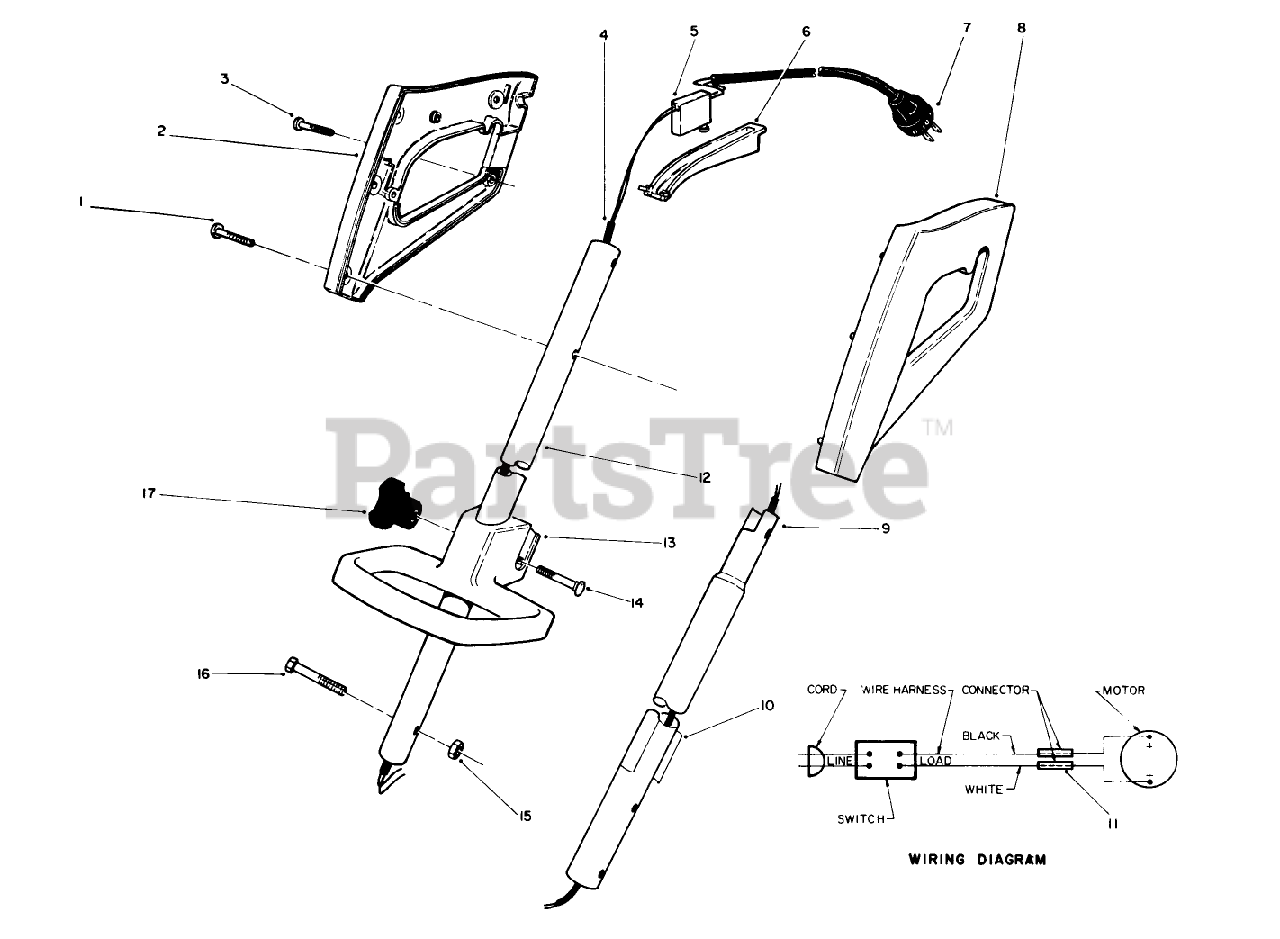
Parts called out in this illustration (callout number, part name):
3	SCREW-PPH
10	Decal-UL
14	BOLT-CARR
15	NUT-LOCK, NI
